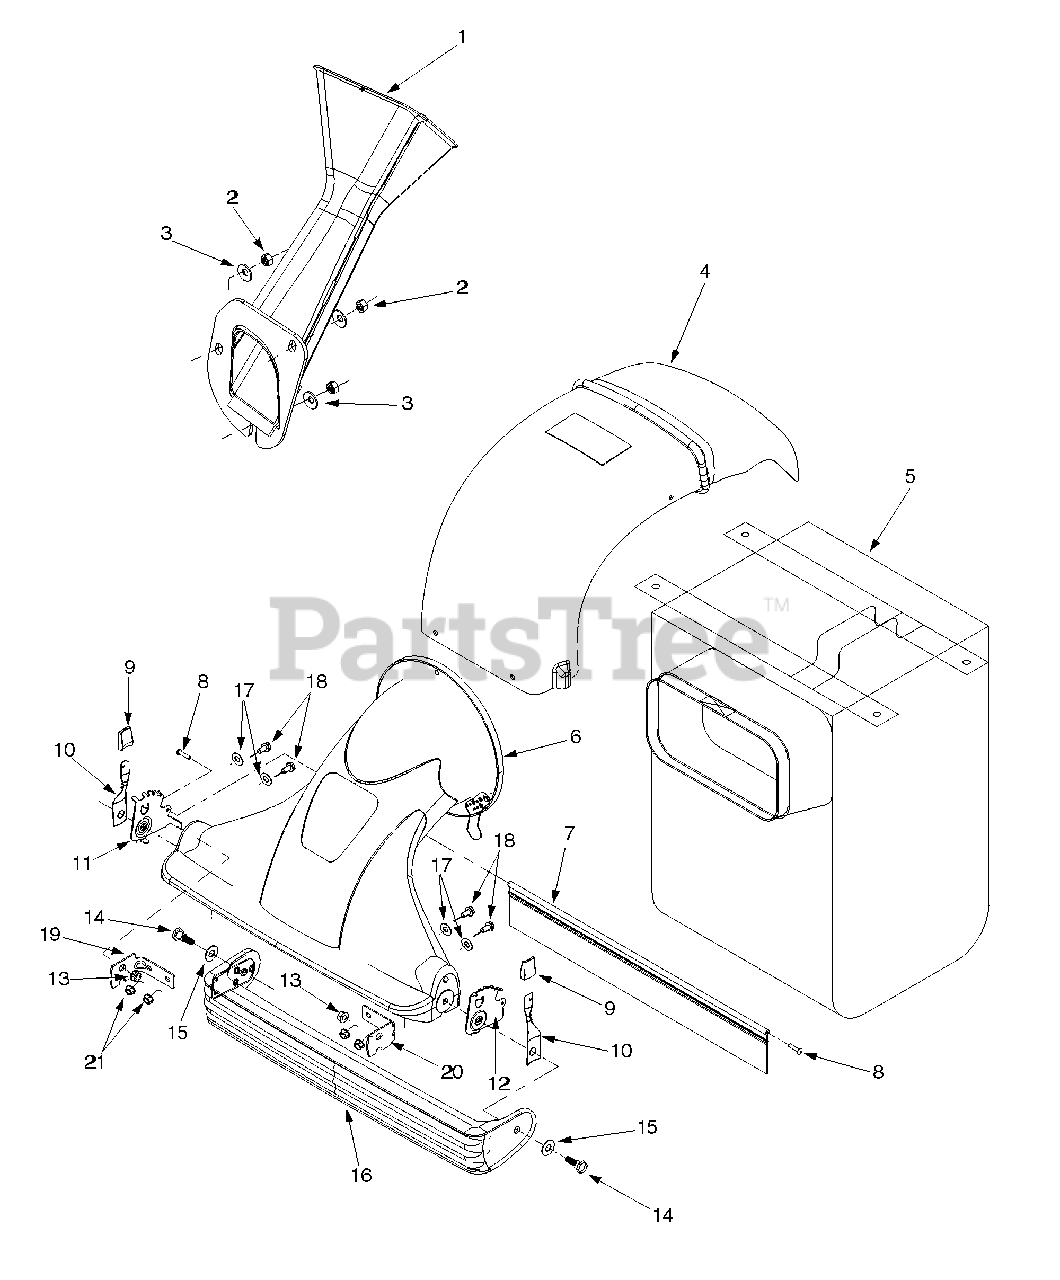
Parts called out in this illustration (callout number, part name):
2	Hex Nut 5/16-18
3	Bell Washer .340 ID x .872 OD
4	Discharge Chute
5	Bag
6	Nozzle Asm
7	Nozzle Flap
9	Height Adjustment Knob
10	Spring Lever
13	Hex Flange Lock Nut 3/8-16
14	Shoulder Screw
15	Flat Washer .510 x 1.12 x .060
17	Flat Washer .28 ID x .74 OD
18	Hex Cap Screw 1/4-20 x .625
19	Nozzle Reinforcement Bracket RH
20	Nozzle Reinforcement Bracket LH
21	Hex Flange Lock Nut 1/4-20
